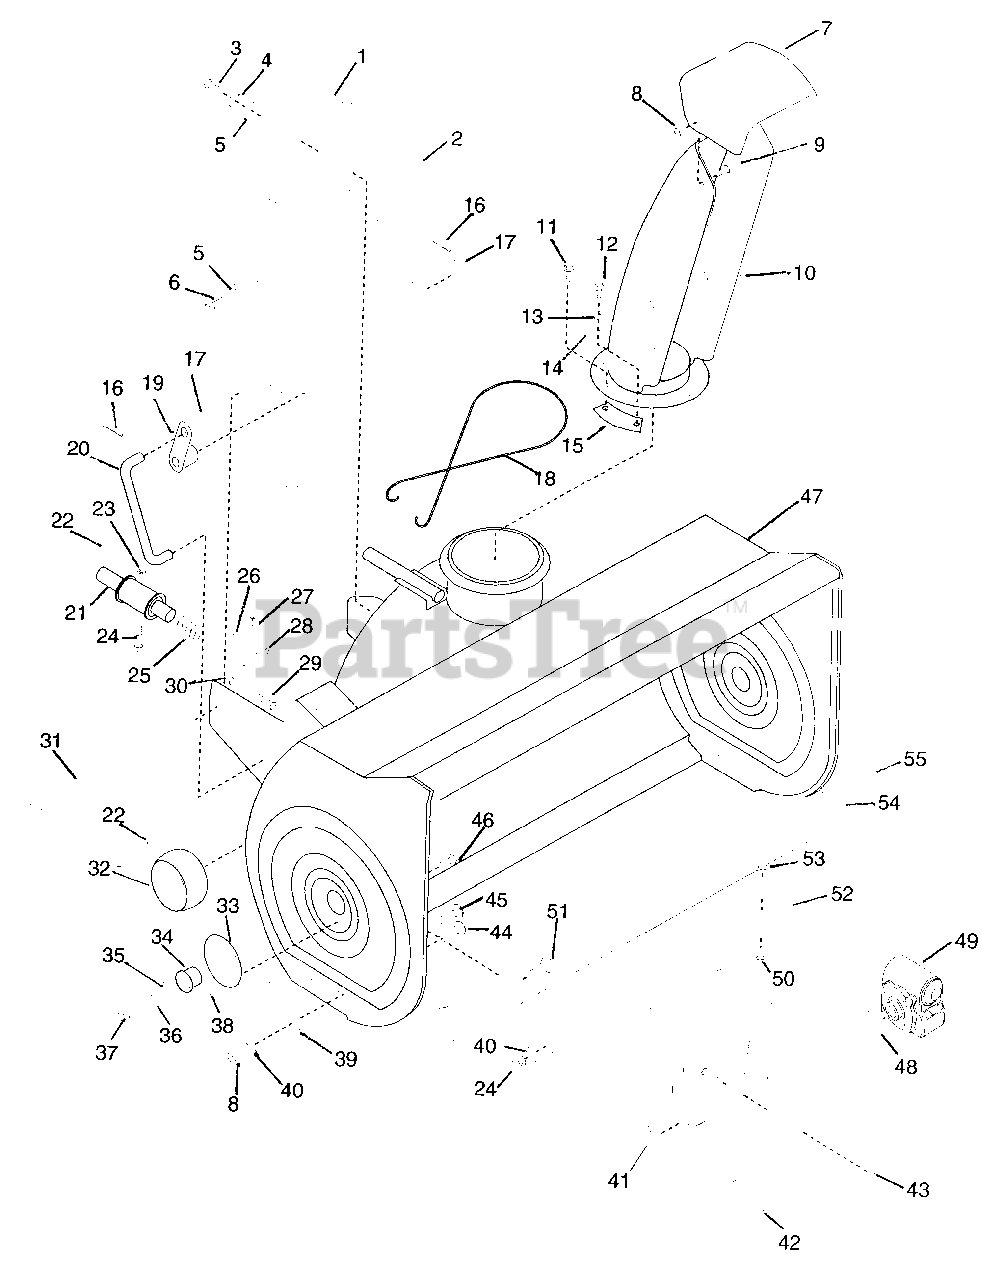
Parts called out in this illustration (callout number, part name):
1	BELT GUARD
2	SHIELD
3	BLT-HEX .31-18X.75 PL GR5
4	WSHR-LK .312X.097 PL HVY
5	WSHR-FL-STL .382X.812X.062
6	SCR-TAP .312-18X.50 HWH PL TR
7	DEFLECTOR W/DECAL
8	NUT-LK-CTR .375-16 GR A PL
9	BLT-HEX .38-16X.75 PL GR2
10	DISCHARGE CHUTE
11	SCR-TAP 12-24X.50 TORX YWZC TR
12	SCR-TAP 12-24X.75 TORX PL TR
13	WSHR-FL-STL .188X.438X.049 PL
14	CABLE CLAMP
15	CHUTE CLAMP
16	PIN-HAIR INT .17X.68X3.50 PL
17	WSHR-FL-STL.656X1.312X.095 PL
19	ARM, LIFT
20	LINK, LIFT
21	HOUR METER
22	PIN-HAIR INT .08X.38X1.42 YWZC
23	NUT-HEX .250-20 PL
24	BLT-RDHDSQNK .25-20X.75 GR5PL
25	SG-COMP .054X.75X1.6
26	WSHR-FL-STL .640X1.005X.062 PL
27	PIN-ROLL .188X1.00
28	DISC ASSEMBLY
29	SCR-SKH 10-24X.38
30	NUT-LK DUAL FACE 10-24 PL
31	RH FOOT REST BRACE
33	BEARING SUPPORT
34	BSHG-FLG 1.000X1.12X.62X1.50BR
35	WSHR-FL-STL .511X1.441X.125 PL
36	WSHR-LK .500X.151 HVY PL
37	BLT-HEX .50-13X1.00 PL GR2
38	NUT-LK-FLG .250-20 PL
39	RUNNER-SKID SHOE
40	WSHR-FL-STL .38X.875X.083 PL
41	WSHR-FL-STL 1.010X1.505X.062PL
42	RAKE, RIGHT-36"(1ID X 15.75OD)
43	SHEAR BOLT SERVICE ASSEMBLY
44	BLT-RDHDSQSHNK .38-16X1.00 PL
45	BLT-RDHDSQNK .38-16X.75 SHT PL
46	BLT-SERNK SL .25-20X.50 PL
47	36" SNO-THRO HOUSING
48	SEAL 1.625X2.125X.250
49	GEAR CASE - 40" - CAST IRON
50	BLT-HEX .38-16X.75 PL GR5
51	BLT-RDHDSQNK .31-18X.75 SHT PL
52	BLADE BRACE
53	NUT-LK TOP .375-16 GR C YWZC
54	SCRAPER BLADE 36"
55	BLT-RDHDSQNK.31-18X.88 GR5YWZC
